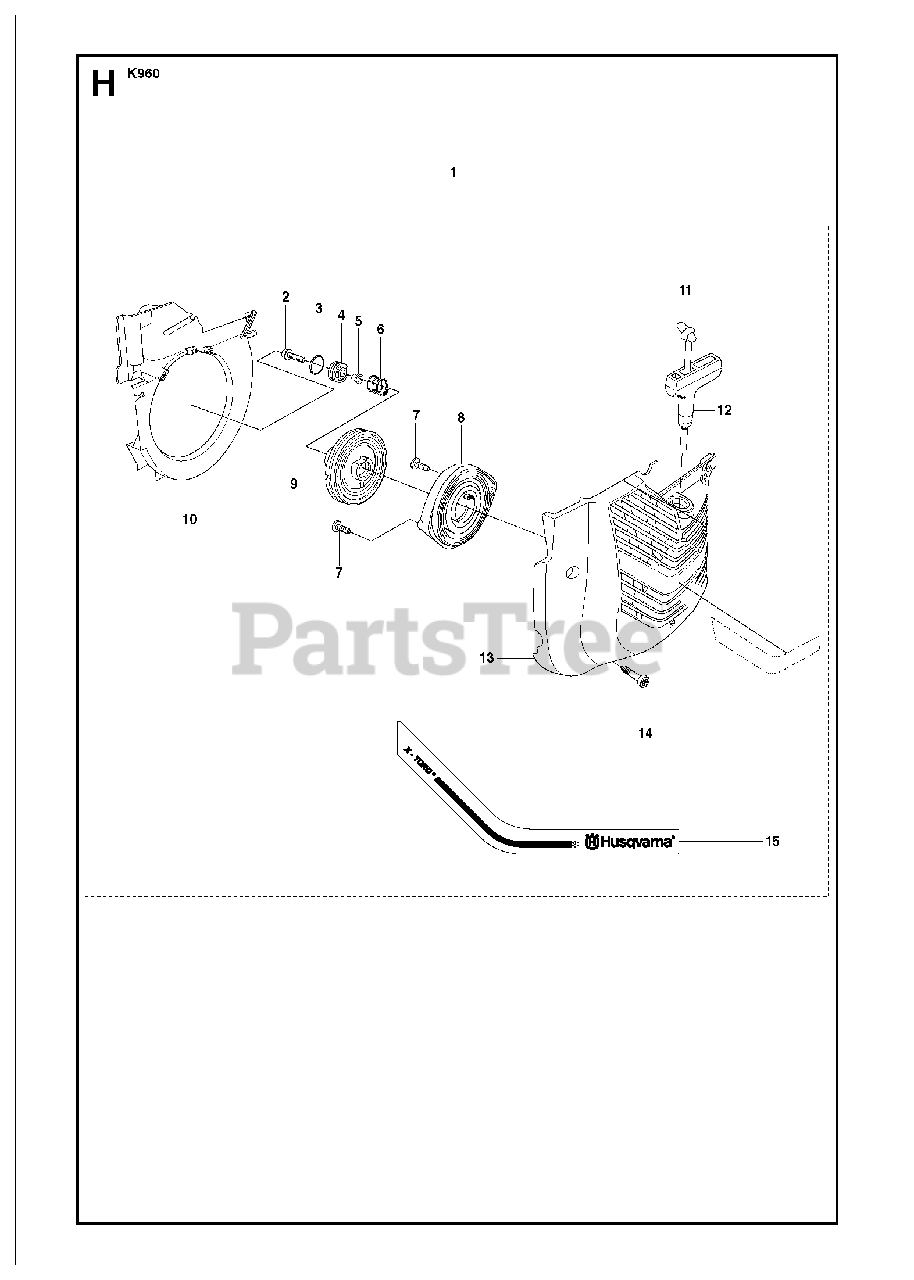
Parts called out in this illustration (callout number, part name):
1	STARTERIncl. 2 - 15
2	SCREW IHSCT
4	GROMMET
5	SPACING SLEEVE
6	COMPRESSION SPRING
7	SCREW CCRPANT
8	RECOIL SPRING
9	STARTER PULLEY
10	AIR CONDUCTOR
11	STARTER CORD50 m Coil
12	STARTER HANDLE
13	STARTER COVER
14	SCREW ITXSCM
